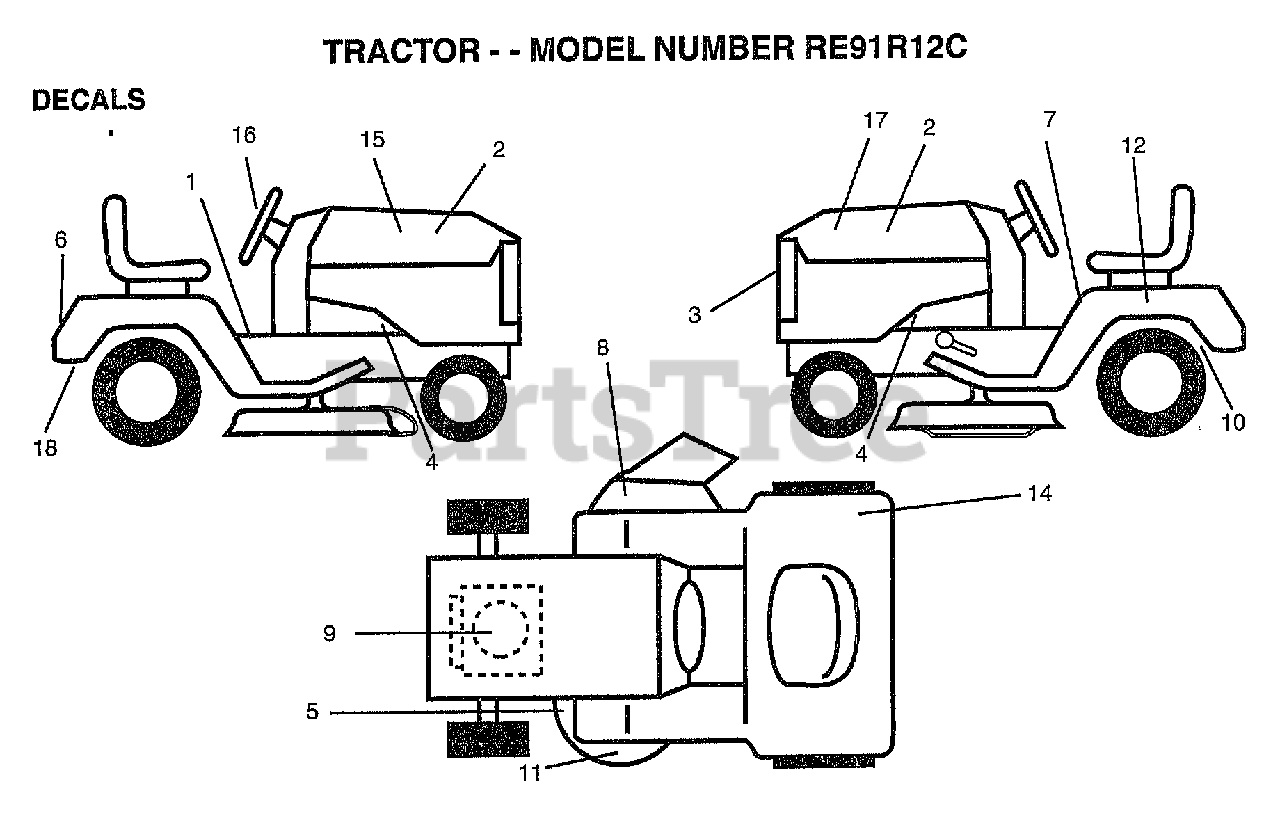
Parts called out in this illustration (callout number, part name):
1	DECAL CLUTCH/BRAK
2	"DECAL INSERT,HOOD"
3	GRILL DECAL
4	"DECAL CHASSIS,HOT"
5	DECAL.V.BELT
6	FENDER DECAL
7	DECAL.READ.O.MANU
8	DECAL.DANGER.CUTF
10	DECAL.DRAWBAR.LDL
12	DECAL.BATRY.3-3908
15	DECAL HD RLY RH
16	"DECAL,STR WHL"
17	DECAL HD RLY LH
18	DECAL.EURO.ST.CE.
